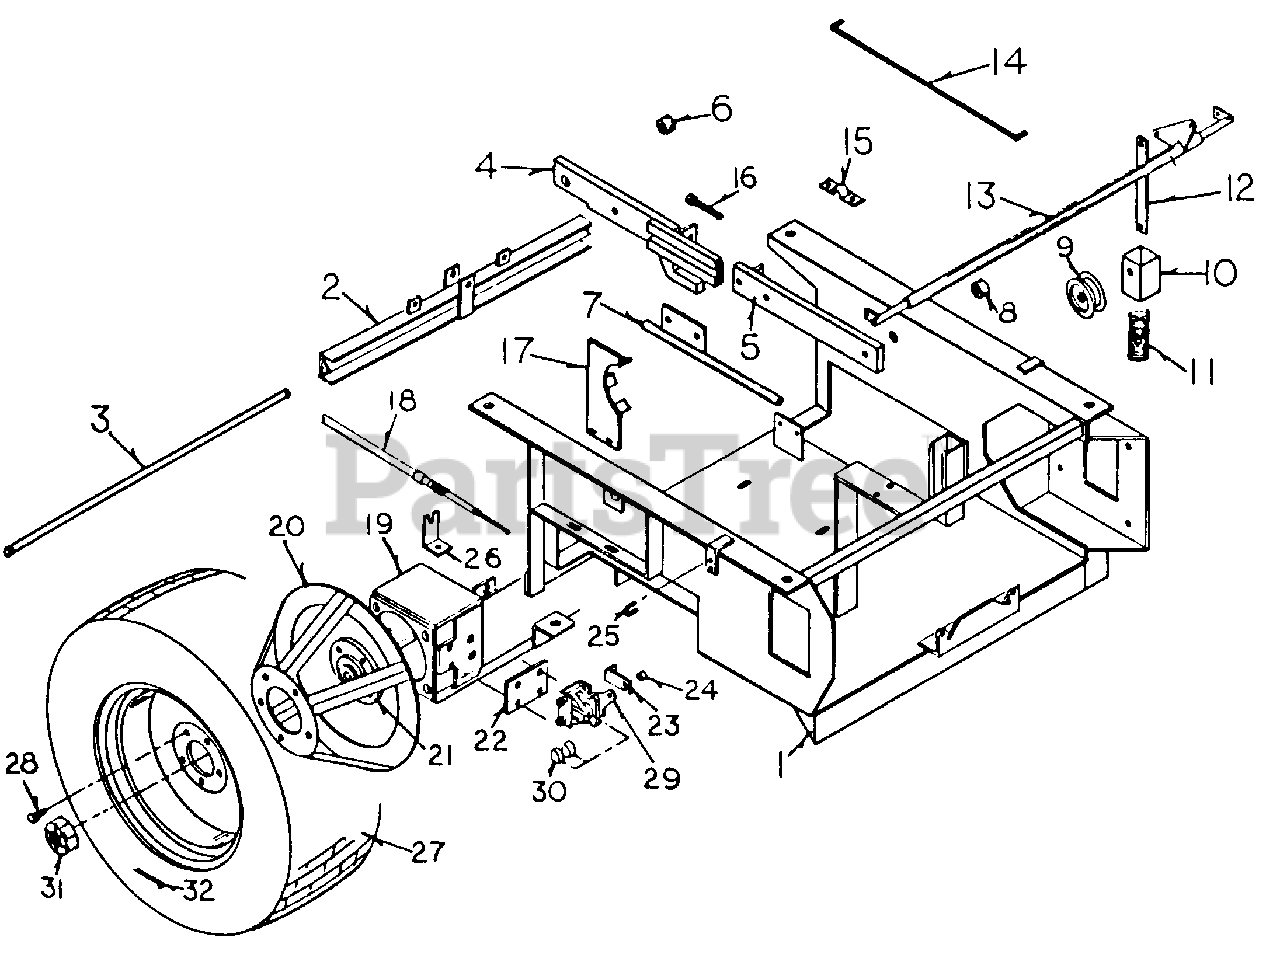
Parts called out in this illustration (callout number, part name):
1	Base
2	Lift Bar
3	Cross Bar Pin
4	RH Deck Lift Arm, Front Adjustable
5	Deck Lift Arm, Back
6	Bushing, Long
8	Bushing, Short
9	Idler Pulley 1
10	Spring Loaded Idler Mount
12	Pivot Bar Linkage
13	Brake Clutch Rod
14	Brake Pedal Rod
15	Cross Rod Bearing
16	Deck Arm Adjusting Bolt
19	Axle
21	5 Bolt Hub
22	Brake Caliper Mount
23	Cable End
24	Bushing
25	Clamp
26	Cable Dead Head
27	Tire Assembly, 20 x 8.00-10 0
29	Brake Caliper, LH
32	Cotter Key
